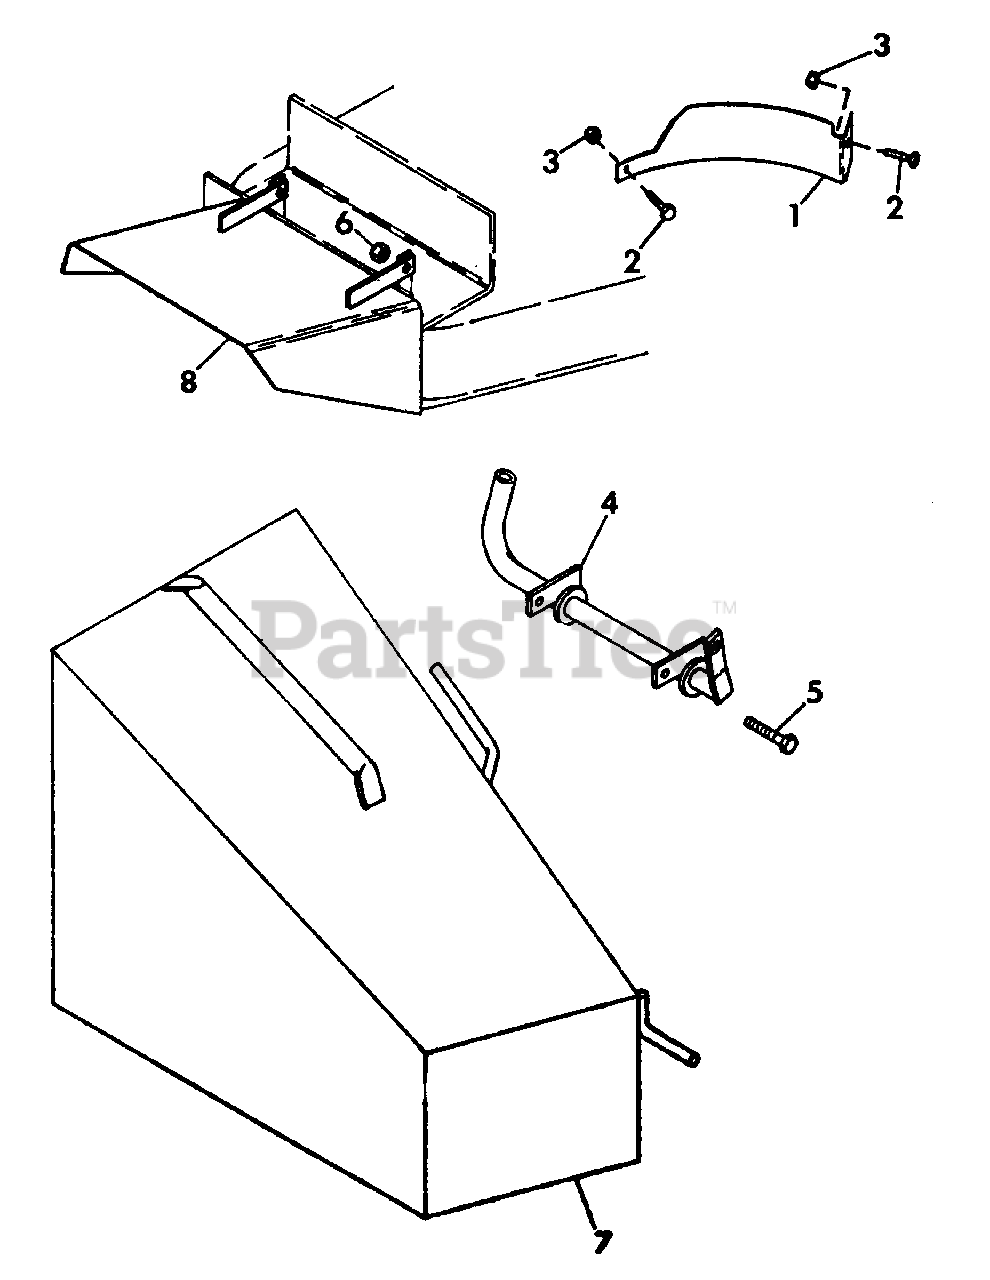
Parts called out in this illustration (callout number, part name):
1	BAFFLE
2	BOLT, 1/4-20X.75 RD HD SQ NK
3	NUT, LOCK 1/4-20
4	WELDMENT, TUBE
5	BOLT, HEX 5/16-18X1.25
6	NUT, LOCK 5/16-18
7	BASKET, WIRE MESH
8	WELDMENT, DISCHARGE CHUTE
